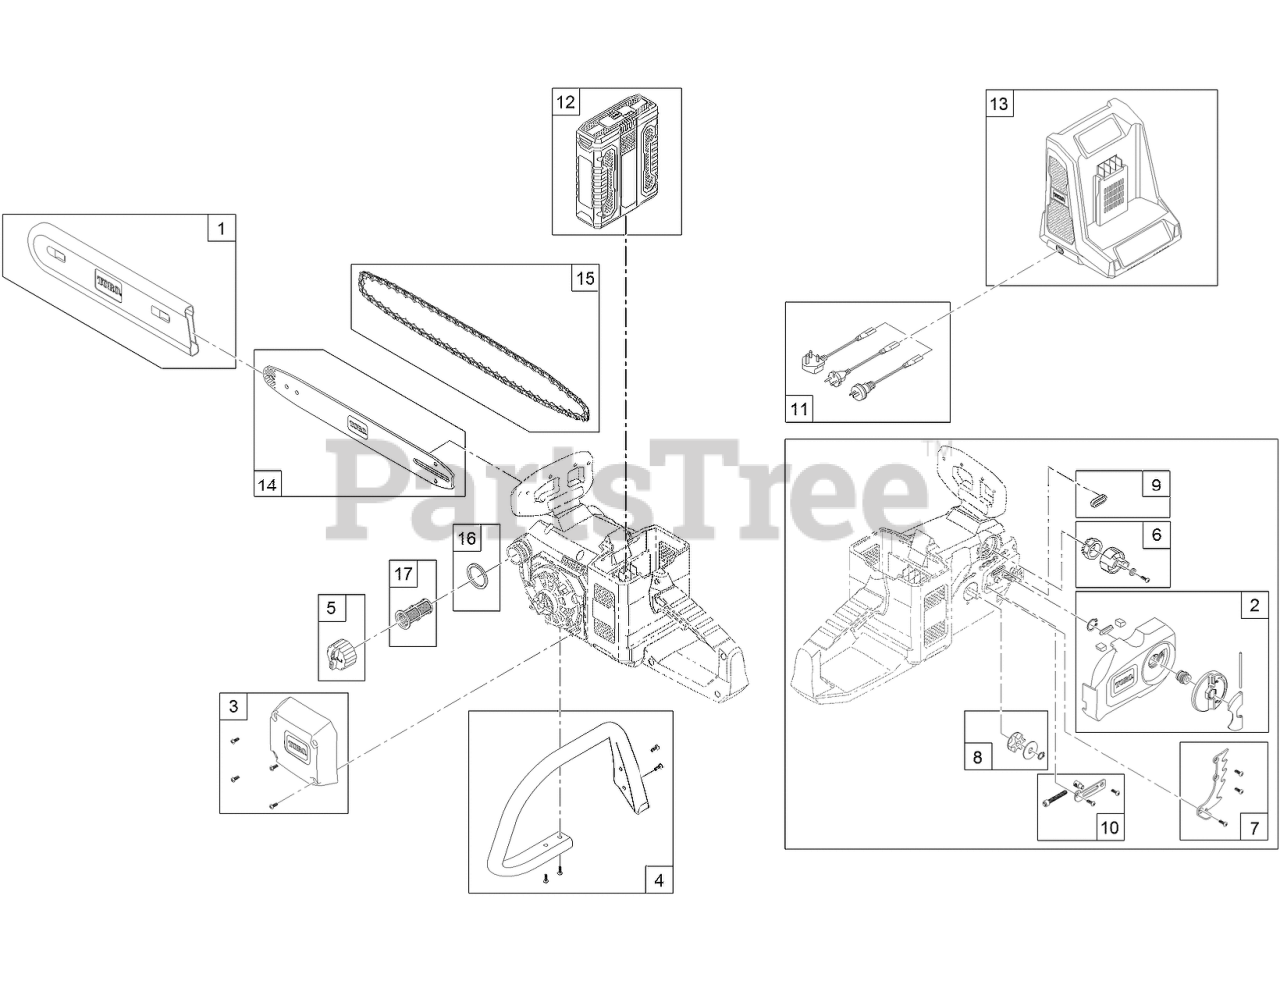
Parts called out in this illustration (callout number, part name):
1	SLEEVE-BAR/CHAIN
2	CHAIN BAR PANEL ASM
3	COVER-MOTOR
4	HANDLE
5	CAP-OIL, BAR
6	ADJUSTER KNOB WITH BAR AND CHAIN ASM
7	BUCKING TEETH BRACKET ASM
8	SPROCKET-DRIVE, CHAIN
9	GASKET-OIL, BAR/HOUSING
10	ADJUSTER BAR WITH PIN AND SCREW ASM
11	CORD SET
12	BATTERY-40V MAX
13	CHARGER-BATTERY, 40V MAX
14	Bar-REPLACEMENT
15	CHAIN
16	GASKET-OIL CAP, BAR
17	STRAINER-OIL, BAR
